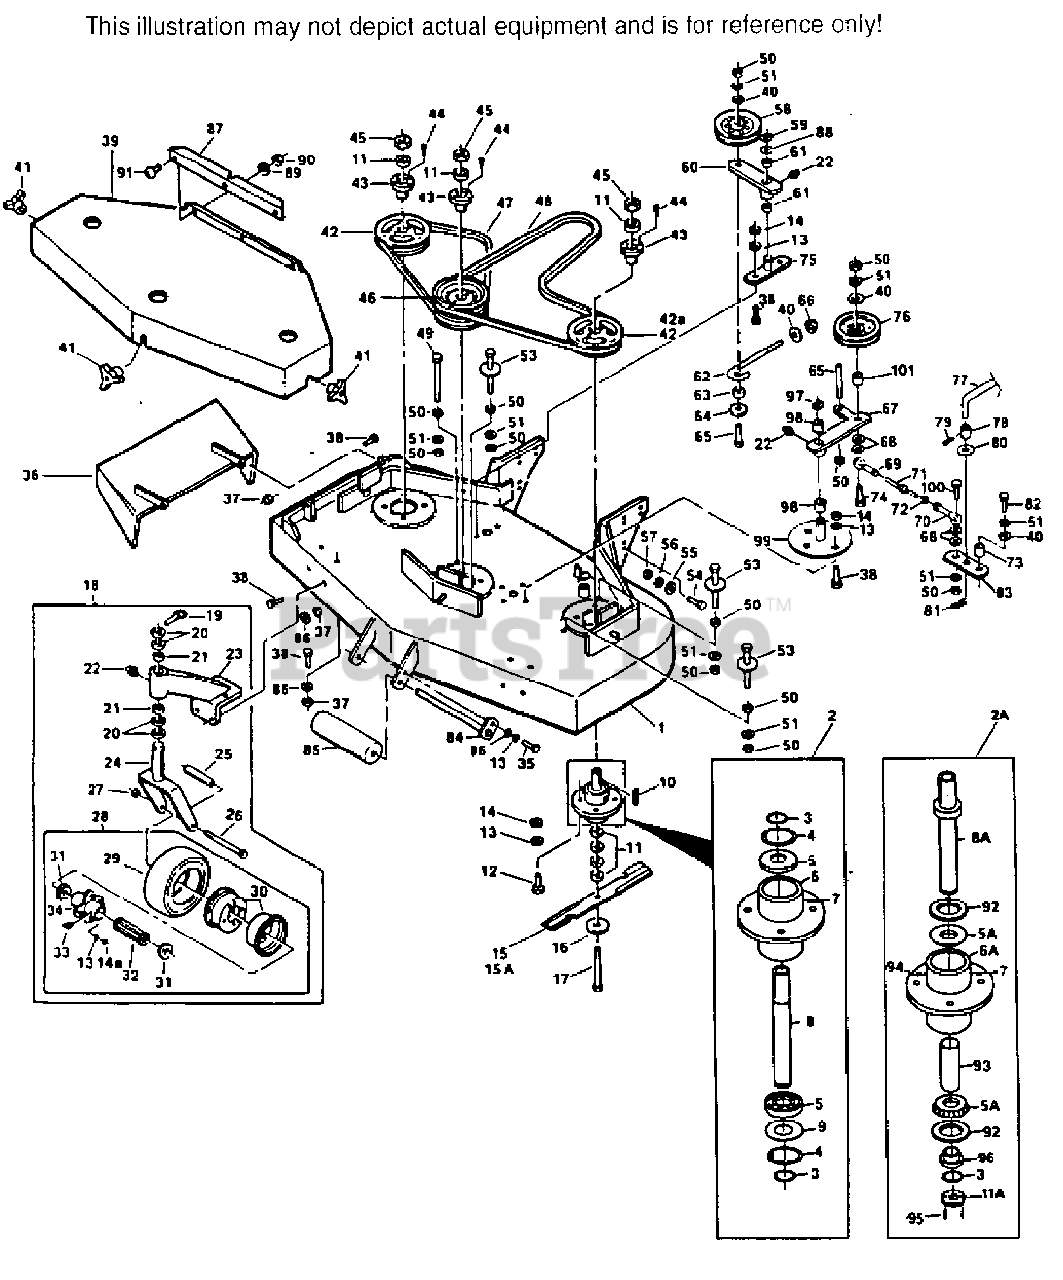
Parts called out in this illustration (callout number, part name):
1	CUTTER DECK(INCLUDES DECALS)
2	CUTTER SPINDLE ASSY.(INCLUDES 3-9)
2A	SPINDLE ASSEMBLY, TAPERED BEARING
3	RETAINING RING, 1" EXT.-INVERTED
4	RETAINING RING, 2-7/16 INT.-BASIC
5	BEARING, CUTTER SPINDLE
5A	TAPERED BEARING
6	SPINDLE HOUSING
6A	SPINDLE HOUSING, TAPERED BEARING
7	GREASE FITTING, STR. 5/16 SERR.
8	SPINDLE, CUTTER BLADE
8A	SPINDLE SHAFT, TAPERED BEARING
9	WASHER, 1-15/16 X 2-13/32 X 16 GA.
10	KEY, 1/4 X 1/4 X 2
11	SPACER, CUTTER BLADE
11A	SPACER, CUTTER BLADE
15	CUTTER BLADE, 18" STD.
15A	CUTTER BLADE, 18" HI LIFT
16	FLAT WASHER, 5/8
17	HEX HEAD BOLT, 5/8-11 X 9-1/2
18	CASTER ASSY, COMPLETE(INCLUDES 19-28)
19	QUICK PIN
20	SPACER, CASTER YOKE, 1/2 LONG
21	BRONZE BEARING
22	GREASE FITTING, STR. 1/4-28
23	SUPPORT ASSY.(INCLUDES 21-22)
24	CASTER YOKE
25	SLEEVE, CASTER WHEEL BEARING
26	HEX HEAD BOLT, 1/2-13 X 5-1/2
28	WHEEL ASSY.(INCLUDES 13-14, 14A, 29-34)
29	TIRE ONLY, CASTER WHEEL
30	RIM PAIR, CASTER WHEEL
31	RETAINER, BEARING, CASTER WHEEL
32	ROLLER BEARING, CASTER WHEEL
33	GREASE FITTING, 45' 1/4-28
34	HUB ASSY, W/BOLTS, CASTER WHEEL
36	DISCHARGE CHUTE
37	HEX NUT, 5/16-18 ELASTIC STOP
39	BELT COVER(INCLUDES DECALS)
41	WING NUT, 3/8-16
42	PULLEY(INCLUDES 43-44)
43	TAPER HUB
46	PULLEY, DOUBLE(INCLUDES 43-44)
47	BELT, RH BLADE DRIVE
48	BELT, BLADE DRIVE
51	LOCKWASHER, 3/8 SPRING
53	BELT GUIDE
57	HEX NUT, 1/2-13 ELASTIC STOP
58	PULLEY
59	RETAINING RING, 3/4" EXT. - "E"
60	IDLER ARM ASSEMBLY(INCLUDES 22 & 61)
61	BRONZE BEARING
62	J ROD, IDLER PULLEY
63	SPACER
64	WASHER, 3/8 X 1-1/2 X 16 GA.
66	HEX NUT, 3/8-16 ELASTIC STOP
67	IDLER ARM(INCL. 22 & 98)
69	ROD END LH THD(SILVER)
70	ROD END RH THD(GOLD)
71	LINK, TURNBUCKLE
73	SLEEVE, CAM CLUTCH
75	IDLER PIVOT
76	PULLEY, IDLER
77	BLADE CLUTCH ROD
78	SLEEVE, CLUTCH ROD
80	FLAT WASHER, 33/64 X 1 X 16 GA.
81	HAIR PIN, LARGE
83	CAM LINK
84	ROLLER SHAFT
85	GUIDE ROLLER
87	BELT COVER SKIRT
91	MACHINE SCREW, 1/4-20 X 1/2 SLT. TRUSS HD.
92	SEAL, TAPERED BEARING SPINDLE
93	SLEEVE, CUTTER SPINDLE
94	RELIEF FITTING, CUTTER SPINDLE
96	SPINDLE BUSHING
97	RETAINING RING, 1 1/8" EXT - "E"
98	BRONZE BEARING
99	IDLER PIVOT
101	SPACER
